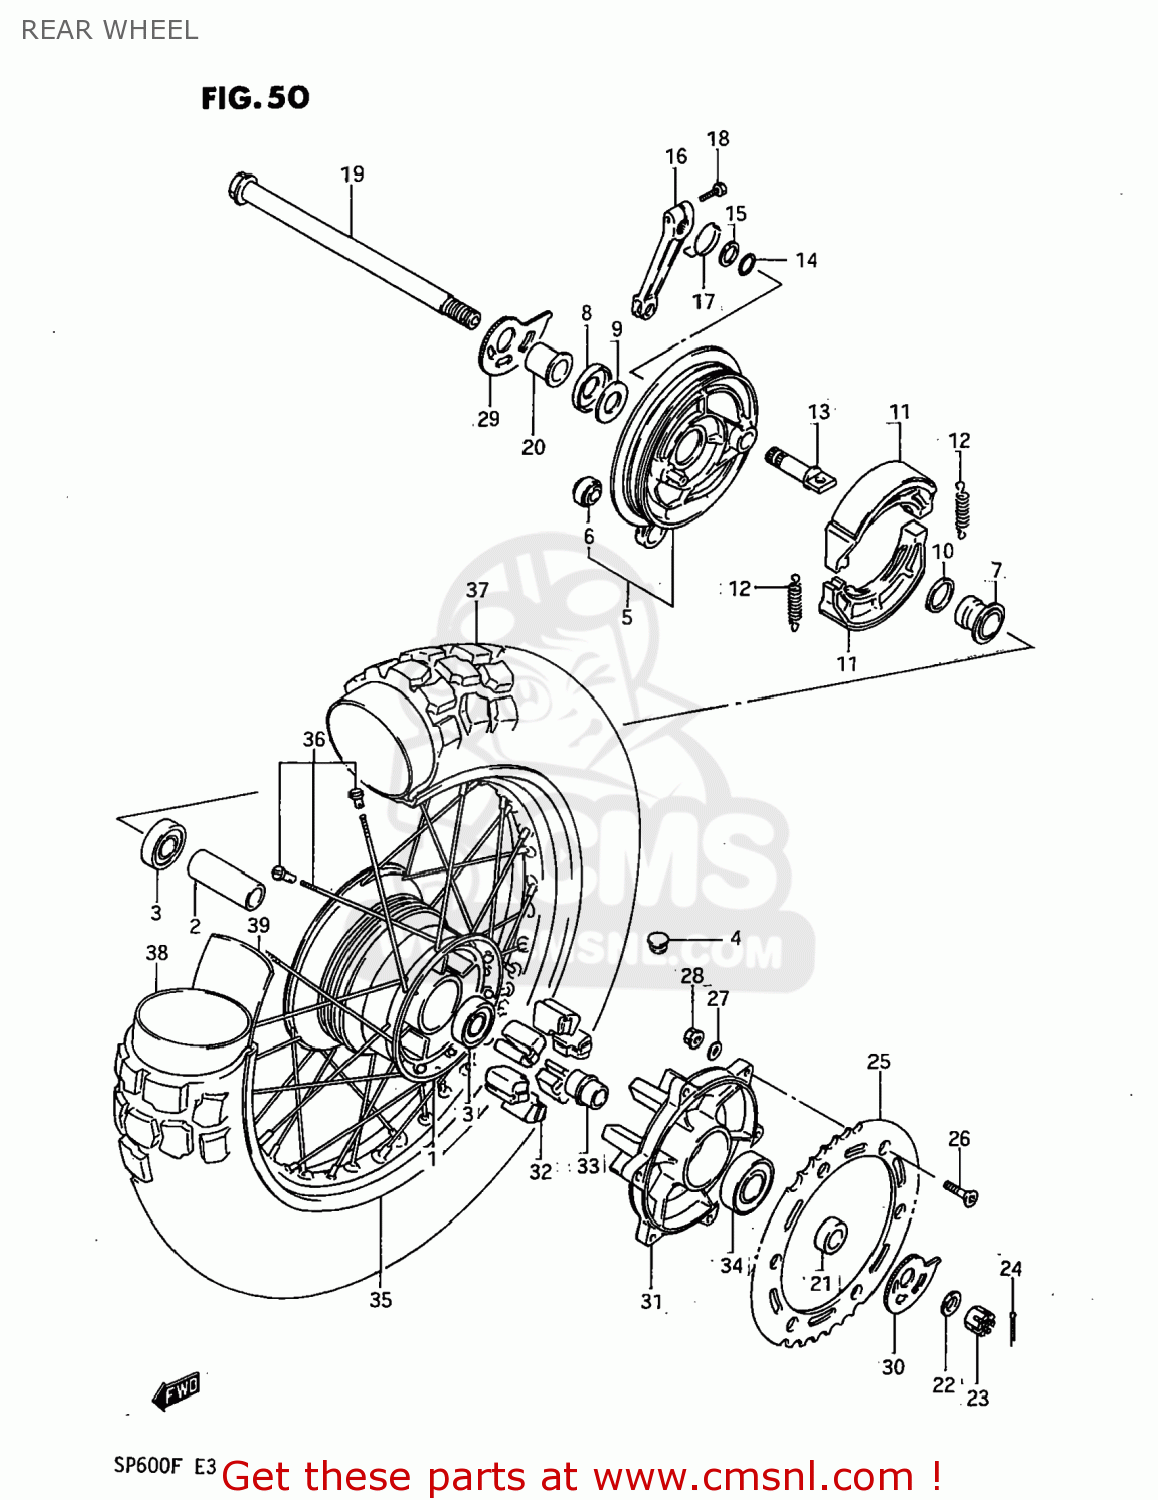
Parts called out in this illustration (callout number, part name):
1	DRUM,REAR HUB
2	SPACER (17.5X25X90)
3	BEARING
4	CAP(OD:12)
5	PANEL SET,REAR HUB
6	SPHERICAL BRNG,TORQUE LINK
7	SPACER,REAR BRAKE ANCHOR
8	CVR,RR BRAKE AHR PNL DUST SEAL
9	WASHER
10	SEAL,OIL(24X31X5)
11	SHOE,BRAKE
12	SPRING(L:34)
13	CAM,REAR BRAKE
14	O-RING (D:2.4 ID:13.8)
15	WASHER (14.5X22X1.6)
16	LEVER,RR BRAKE CAM
17	SPRING
18	BOLT
19	AXLE,RR
20	SPACER,REAR AXLE
21	SPACER (17X33X11)
22	WASHER
23	NUT 16MM
24	PIN,COTTER
25	SPROCKET,REAR
26	BOLT(8X30.5)
27	WASHER
28	NUT
29	ADJUSTER,CHAIN RH
30	ADJUSTER,CHAIN LH
31	DRUM,RR SPROCKET MOUNTING
32	CUSHION,REAR DRUM
33	RETAINER,RR SPROCKET DRUM
34	BEARING
35	RIM,REAR WHEEL (2.50-17)(
36	SPOKE SET,REAR WHEEL
37	TIRE
38	TUBE ASSEMBLY,WHEEL,INNER
39	PROTECTOR,WHEEL,INNER
